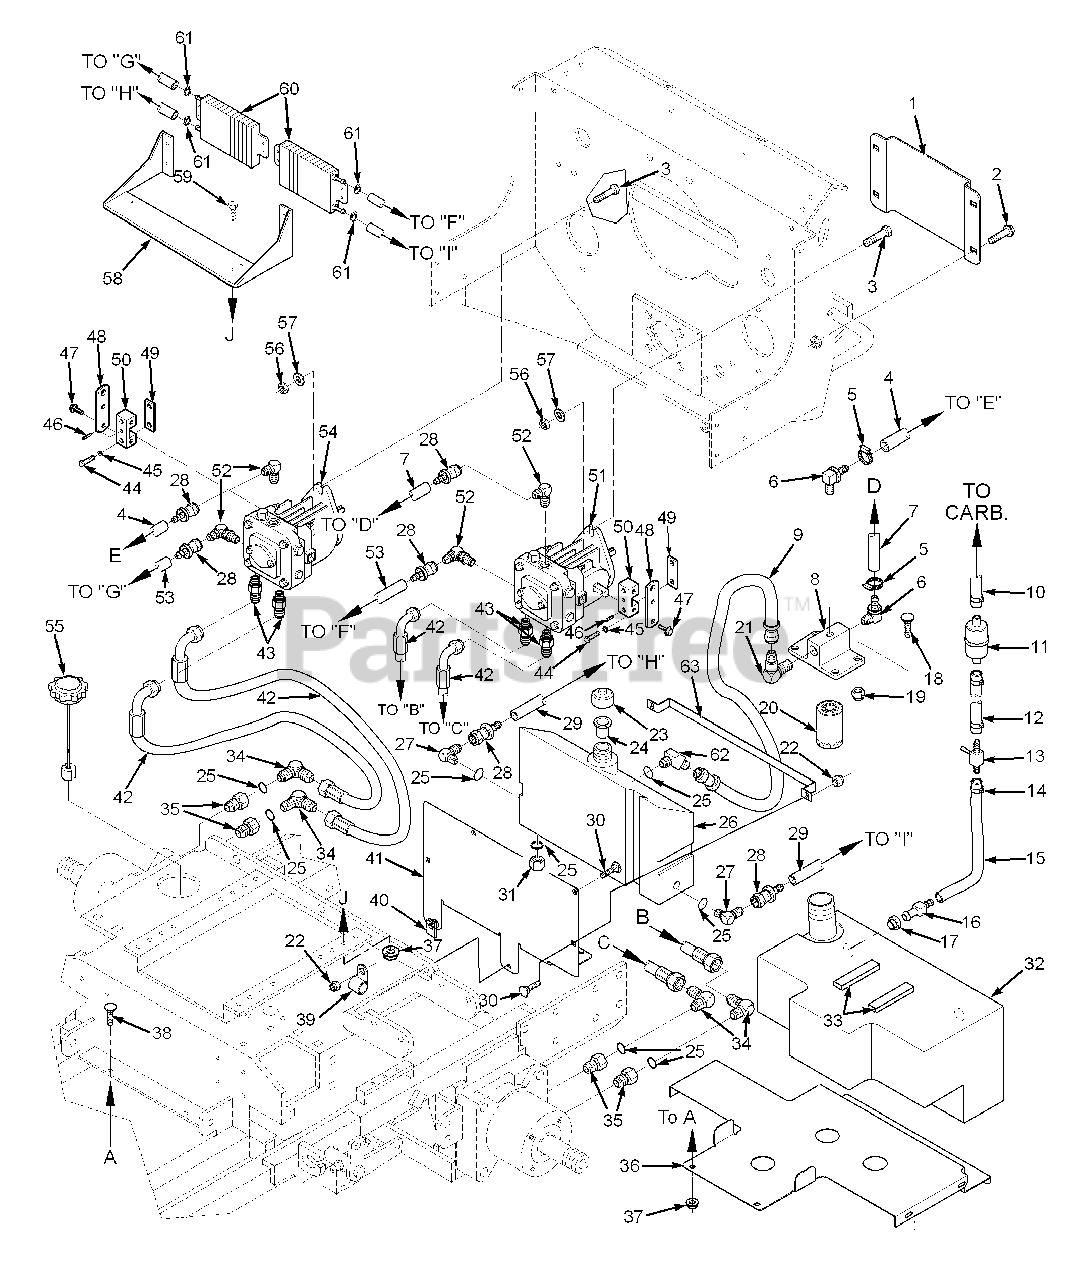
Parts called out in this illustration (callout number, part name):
1	Rear Cover
2	Bolt, Carraige 5/16-18 x .75"
3	Bolt, Hex Head 1/4-20 x 2.0"
4	Hose, 3/8" ID Pushlock - 38.0"
5	Clamp, Hose 1/2"
6	Elbow, 90 Degree - 1/4 NPT x 3/8 Hose
7	Hose, 3/8" ID Pushlock - 10.25"
8	Oil Filter Base
9	Hose Assembly
10	Fuel Hose to Carb.
11	Fuel Filter
12	Fuel Hose, 1/4" ID. - 2"
13	Valve, Shutoff
14	Clamp, Fuel Hose
15	Fuel Hose, 1/4" ID. - 10"
16	Hose Fitting
17	Bushing
18	Bolt, Carraige 5/16-18 x 1.0"
19	Nut, Hex Elastic Stop 5/16-18
20	Oil Filter
21	Elbow, 45 Degree 1/2NPT x 3/4 JIC
22	Nut, Hex Elastic Stop 1/4-20
23	Cap, Hydraulic Tank
24	Insert, Filler Neck
25	O-Ring
26	Oil Reservoir Assembly
27	Elbow, 90 Degree, 9/16-18 JIC x 9/16 O-Ring
28	Coupling, 3/4-16 THD
29	Hose, 3/8 ID. Pushlock - 14.50"
30	Bolt, Carraige 1/4-20 x 1.0"
31	Plug, 3/4-16 O-Ring
32	Fuel Tank Assembly
33	Pad, Rubber
34	Elbow, 90 Degree, 7/8-14 THD
35	Bushing, 7/8-14 JIC x 3/4-16 O-Ring
36	Support Bracket, Fuel Tank
37	Nut, 5/16-18 Serrated Flange
38	Bolt, Carraige 5/16-18 x 3/4"
39	Hose Clamp
40	U-Nut, 1/4-20
41	Support Bracket, Hydraulic Tank
42	Hose Assembly, Pump
43	Union, 3/4-16 JIC x 3/4-16 O-Ring
44	Bolt, Hex Head 1/4-20 x 1-1/4"
45	Lockwasher, 1/4" Spring
46	Roll Pin, Spring 3/16 x 3/4"
47	Bolt, Hex Serrated Flange 1/4-20 x 3/4"
48	Lever, Control
49	Clamp Plate, Pump Control
50	Block, Pump Control
51	Pump, Left Hand, BDP-10A 464
52	Elbow, 90 Degree
53	Hose, 3/8" ID. Pushlock - 25.0"
54	Pump, Right Hand, BDP 110A 464
55	Cap, Fuel Tank W/Guage
56	Nut, Hex Elastic Stop 3/8-16
57	Flatwasher, 3/8" Grade 8
58	Mounting Bracket, Oil Cooler
59	Bolt, Hex Head 5/16-18 x 3/4"
60	Cooler, Oil
61	Clamp, .69 Dia.
62	Elbow, 45 Degree 3/4-16 JIC x 3/4-16 O Ring
63	Strap, Hydraulic Tank
